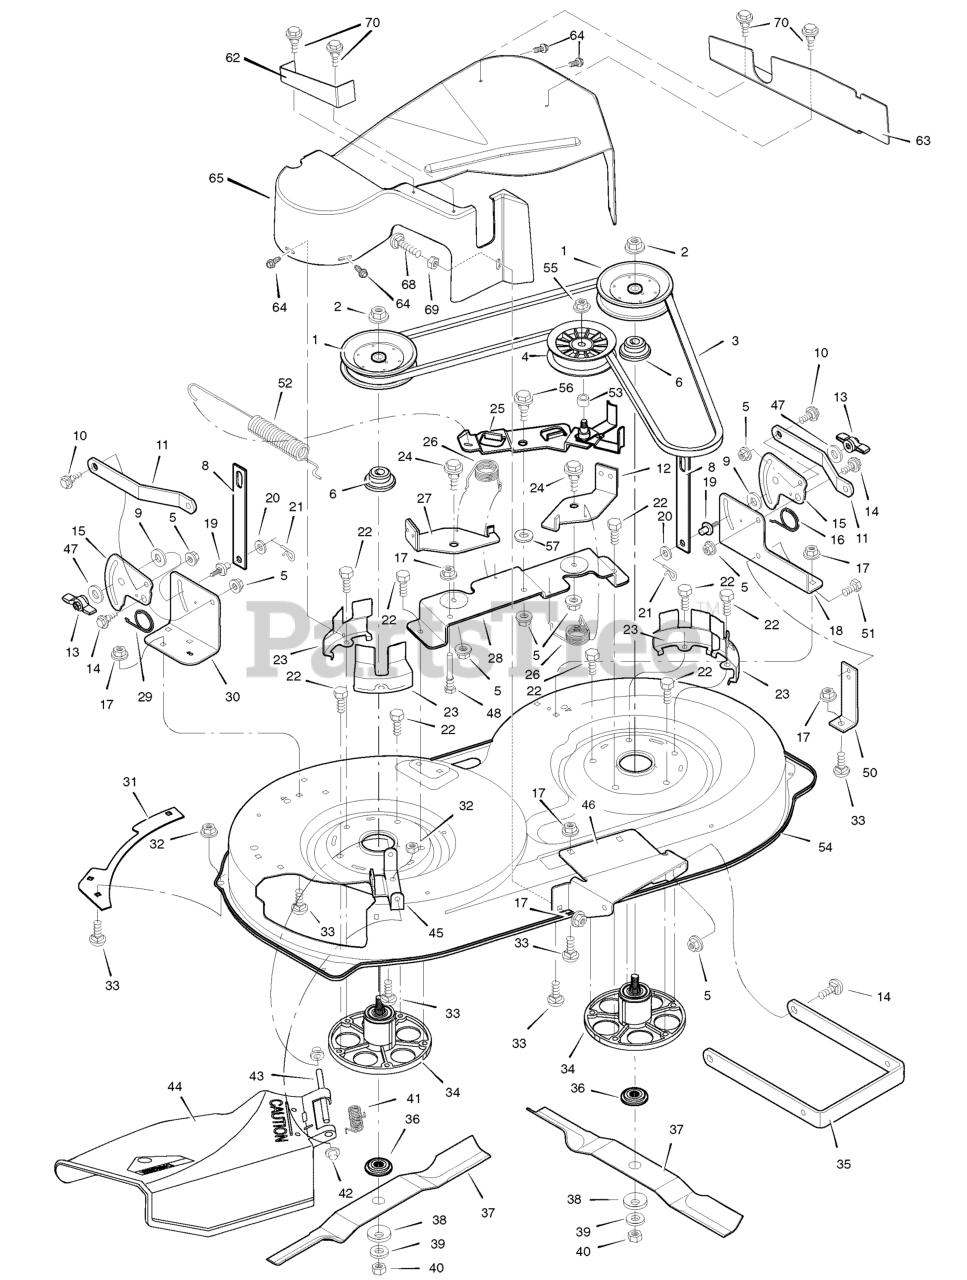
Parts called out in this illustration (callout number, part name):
1	PULLEY, Jackshaft
2	NUT, Hex
3	BELT, Mower Drive
4	PULLEY, Idler
5	NUT, Flange
6	SPACER, Pulley
8	LINK, Lift
9	PAD, Friction
10	BOLT, Shoulder
11	BRACKET, Suspension
12	PAD ASSEMBLY, Left Brake
13	KNOB
14	BOLT, Shoulder
15	PLATE, Suspension
17	NUT, Flange
18	BRACKET, Left Suspension
19	PIN, Hanger
21	PIN, Cotter
23	GUIDE, Belt
24	BOLT, Shoulder
25	ARM, Idler
27	PAD ASSEMBLY, Right Brake
28	BRACKET ASSEMBLY, Brake
30	BRACKET, Right Suspension
32	NUT, Flange
33	BOLT, Carriage
34	MANDRELL
35	BRACKET, Suspension
36	ADAPTER, Blade
37	BLADE
42	CAP, Push On
43	ROD, Deflector
44	DEFLECTOR ASSEMBLY
45	BRACKET, Deflector
46	BRACKET, Front Hanger
48	GUIDE, Belt
50	BRACKET, Support
52	SPRING, Extension
54	HOUSING, Export Blade
55	NUT, Flange
56	BOLT, Shoulder
62	PLATE, Guard 38" RH
63	PLATE, Guard 38" LH
65	COVER, Guard
68	BOLT, Carriage, 5/16-18 x 1.50
69	NUT, Hex Lock 3/8-18
70	SCREW HEXHEAD TAP
